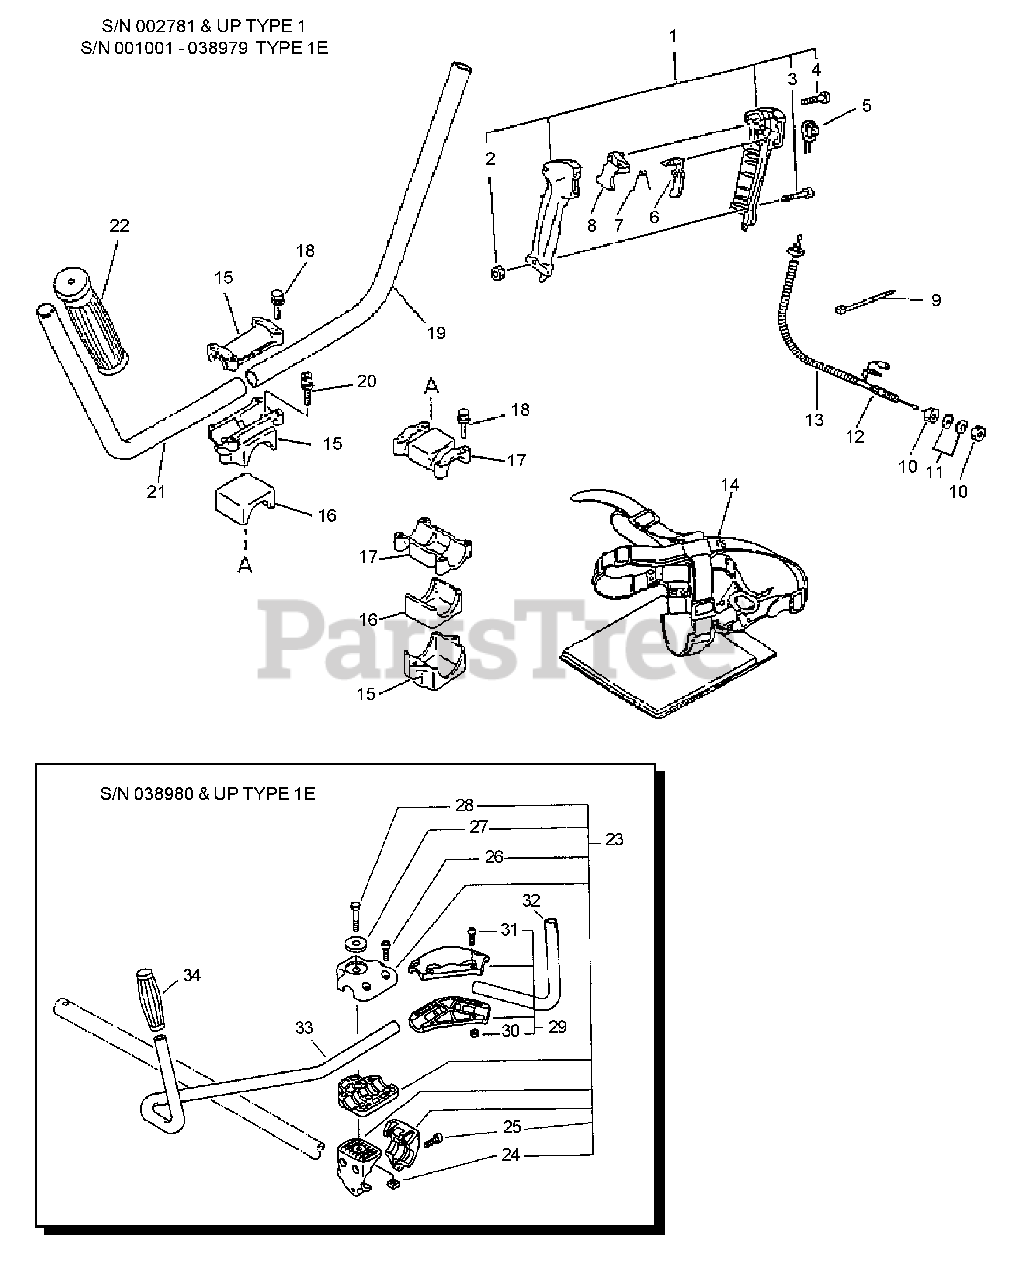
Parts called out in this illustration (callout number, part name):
1	THROTTLE CONTROL ASSY
3	SCREW - 5X30
4	SCREW - 3X25
5	IGNITION SWITCH ASSY
6	LOCKOUT, THROTTLE
7	SPRING, LOCKOUT LEVER
8	TRIGGER, THROTTLE
9	TIE, CABLE - SMALL
11	WASHER - 6
12	CABLE, THROTTLE
14	SHOULDER STRAP ASSY
15	HANDLE BRACKET KIT
16	CUSHION
17	BRACKET ASSY
18	BOLT - 5X25
19	HANDLE - RIGHT
20	SCREW - 5X25
21	HANDLE, FRONT - LEFT
22	GRIP, HANDLE - LEFT
23	HANDLE BRACKET KIT
25	SCREW - 5X30
26	SCREW - 5X20
27	WASHER - 8
28	BOLT - 8X55
29	HANDLE BRACKET KIT
31	SCREW - 5X20
32	HANDLE, FRONT - RIGHT
33	HANDLE, FRONT - LEFT
34	GRIP, HANDLE
